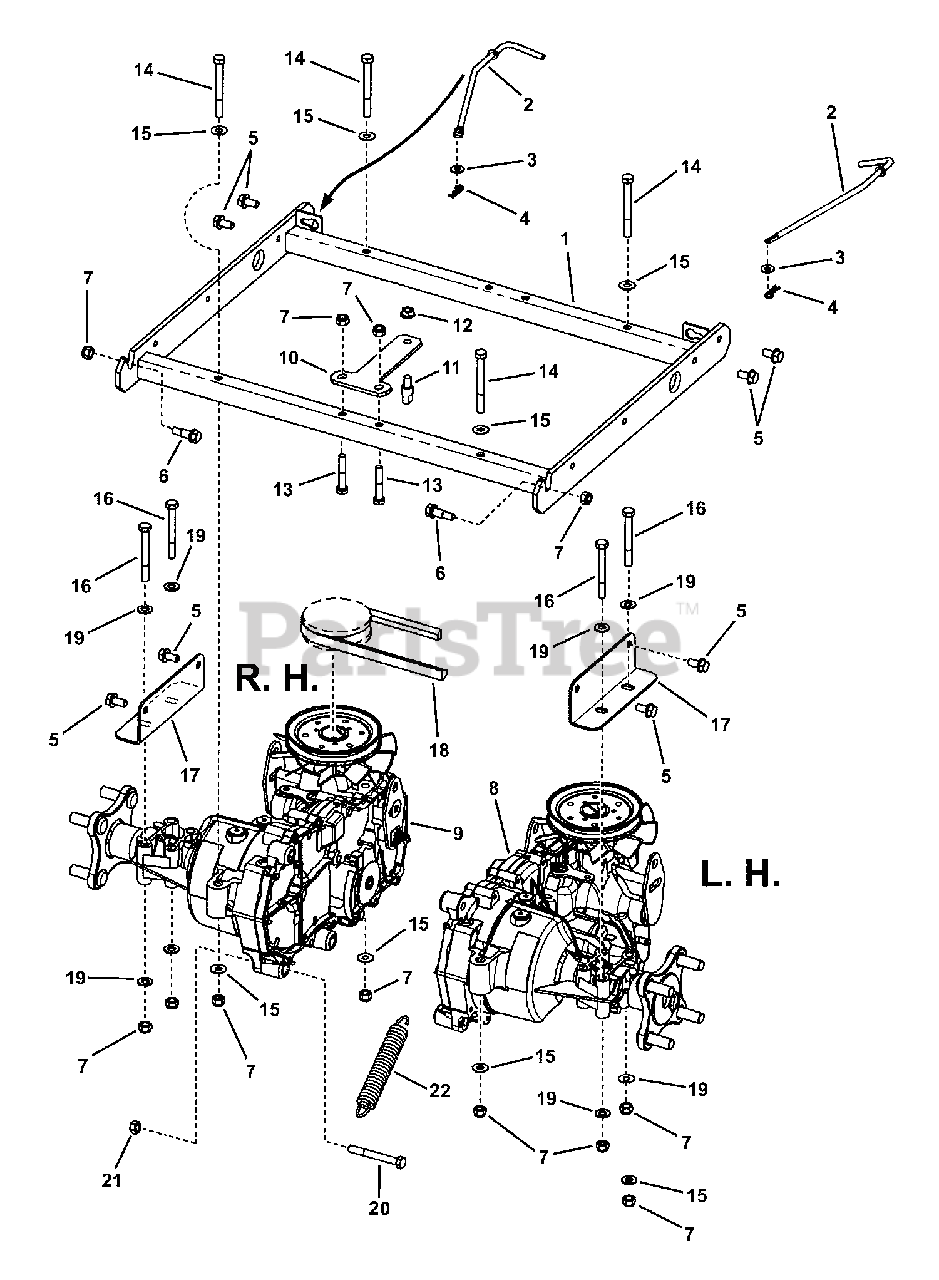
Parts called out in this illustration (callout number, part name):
1	WELD, Transaxle Support
2	ROD, Roll Release
3	WASHER, .28 x .63 x .065 YZ
4	HAIR PIN, 1.12
5	CAPSCREW, Hex Head Flange Taptite, 5/16C x 3/4 YZ
6	BOLT, Shoulder, 5/16C x 1/2, 3/8 DIA, YZ
7	NUT, Hex, Lock, 5/16C ESNA YZ
8	TRANSAXLE, RZT, LH
9	TRANSAXLE, RZT, RH
10	BRACKET, Anti-Rotation
11	PIN, Anti-Rotation, RZT Clutch, Yellow
12	NUT, Hex Flange Lock, 5/16C GR5 YZ
13	CAPSCREW, Hex Head, 5/16C x 1-3/4 GR5 YZ
14	CAPSCREW, Hex Head, 5/16C x 3 GR5 YZ
15	WASHER, Shim, .314 x .75 x .032 BP
16	CAPSCREW, Hex Head, 5/16C x 2-3/4 GR5 YZ
17	BRACKET, Transaxle Support
18	V-BELT, Hydro Drive (HA section, 58.00" effective length)
19	WASHER, .34 x .69 x .08 YZ
20	CAPSCREW, Hex Head, 7/16F x 2-1/2 GR5 YZ
21	NUT, Hex Center Lock Jam, 7/16F GR5 YZ
22	SPRING, Extension
